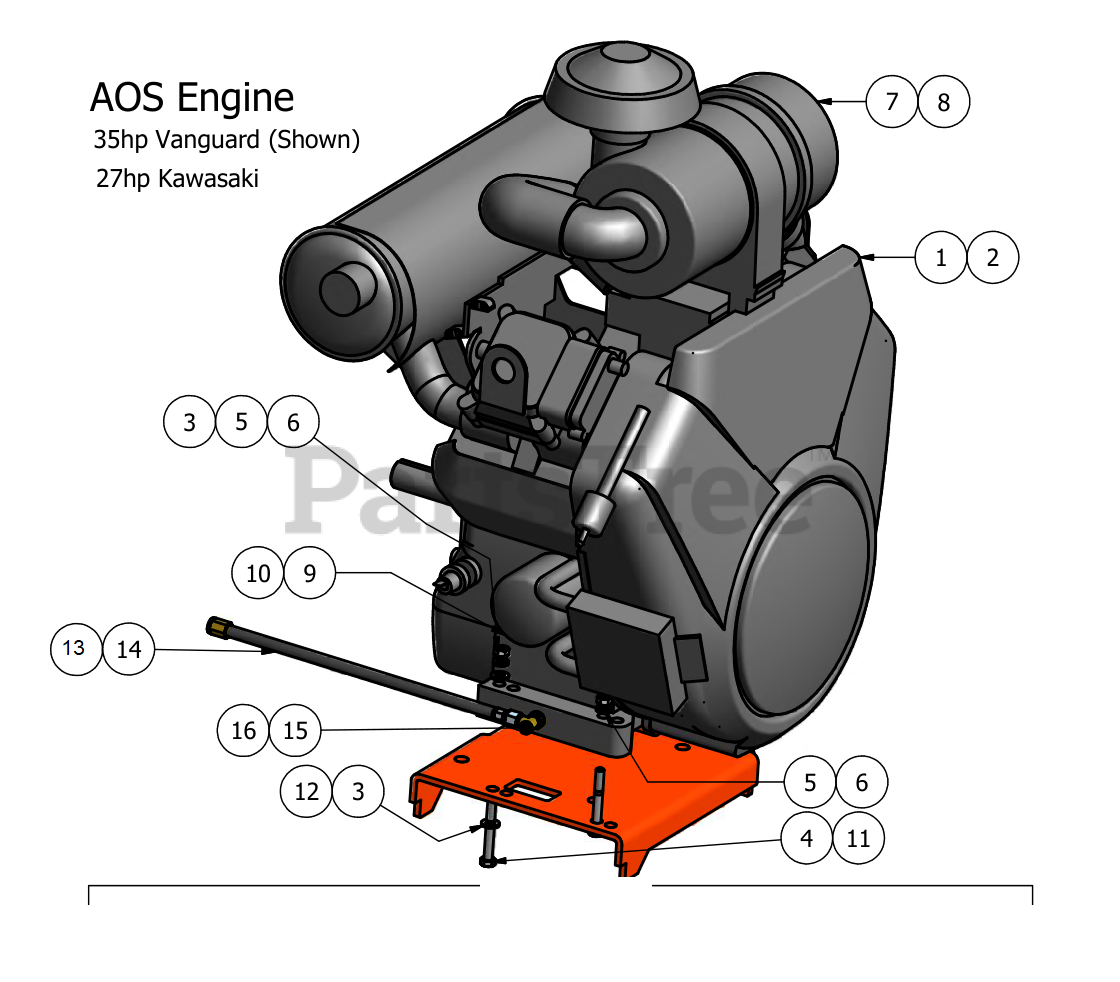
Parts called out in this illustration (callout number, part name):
1	35hp Vanguard Engine
2	27hp Kawasaki Engine with Donaldson Air Filter
3	5/16" Flat Washer (35 Vanguard Only)
4	5/16" x 2 1/2" Bolt (35 Vanguard Only)
5	5/16" Lock Washer (35 Vanguard Only)
6	5/16" Nut (35 Vanguard Only)
7	Air Filter (Outer Canister)
8	Air Filter (Inner Canister)
9	Oil Filter (35hp Vanguard)
10	Oil Filter (27hp Kawasaki)
11	10mm x 552 Bolt (27hp Only)
12	7/16" Lock Washer (27hp Only)
13	Oil Drain Hose (35hp Vanguard)
14	Oil Drain Hose (27hp Kawasaki)
15	Oil Drain Adapter (35hp Vanguard)
16	Oil Drain Adapter (27hp Kawasaki)
17	27hp Kawasaki Wiring Harness
18	35hp Vanguard Wiring Harness
